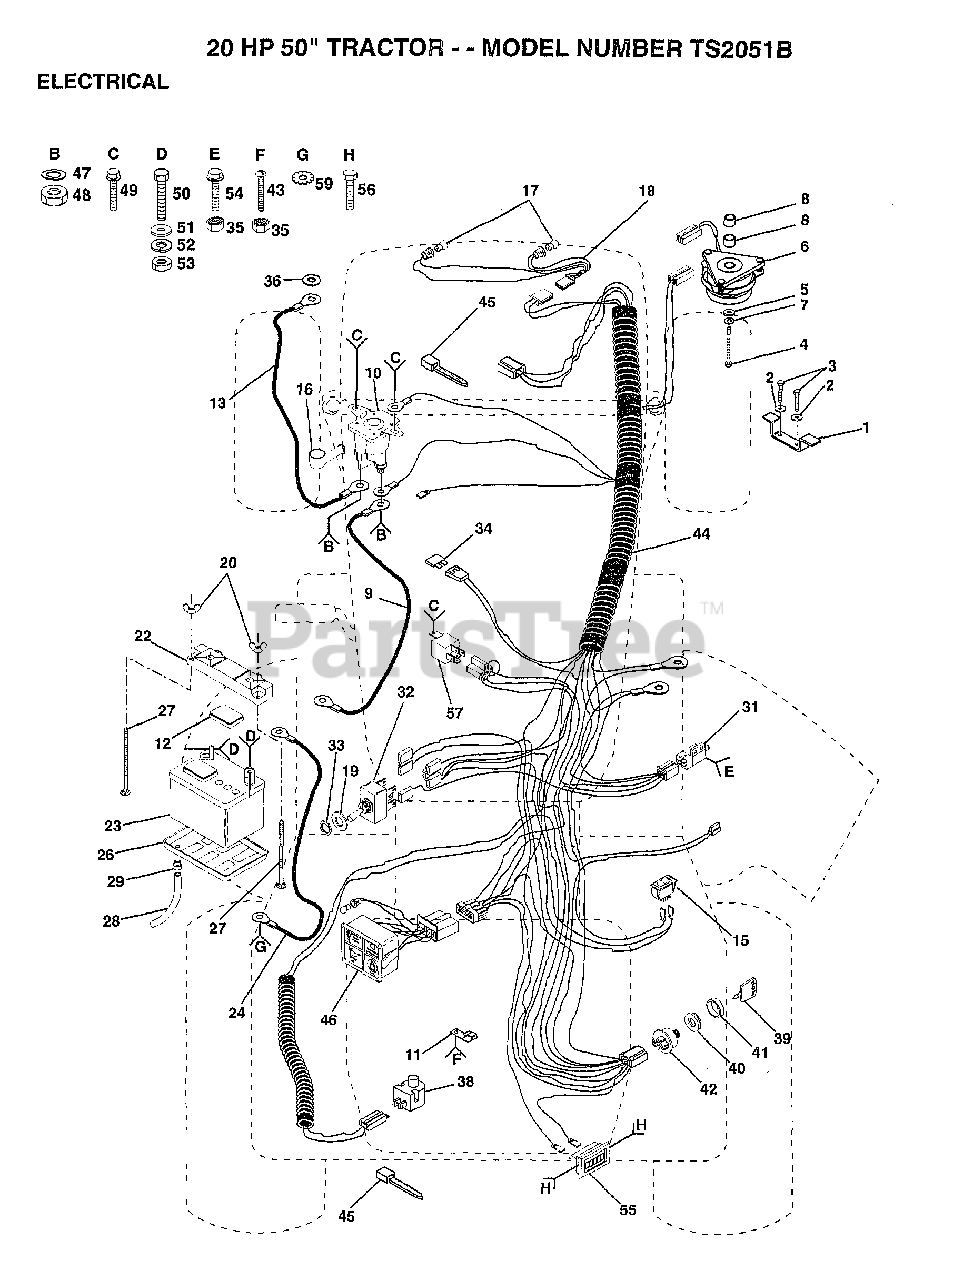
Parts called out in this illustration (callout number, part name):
2	LOCKWASHER
3	BOLT
5	WASHER
7	LOCKWASHER
8	SPACER-CLUTCH
9	CABLE-BATTERY T
12	"CAP,BATTERY "
13	"CABLE,STARTER T"
15	SWITCH LT
17	HEADLAMP BULB
18	"HARNESS,LIGHT SOC"
19	WASHER
24	CABLE T
26	"TRAY T, BATTERY"
27	BOLT
28	"DRAIN TU T, BATT"
29	HOSE CLAMP T
31	SWITCH INTERLOCKT
33	HEX NUT T
34	FUSE HYT
35	"NUT,KEPS"
36	LOCKWASHER
38	SWITCH SEAT
39	KEY
40	NUT IGNITION
44	HARNESS.IGN
45	WIRE TIE
46	LIGHT.PKG.ASM.
48	NUT
49	SCREW
50	BOLT LT
51	WASHER
52	LOCKWASHER
54	SCREW
55	HOUR METER T
56	SCREW
57	RELAY ASSY T
59	LOCKWASHER
